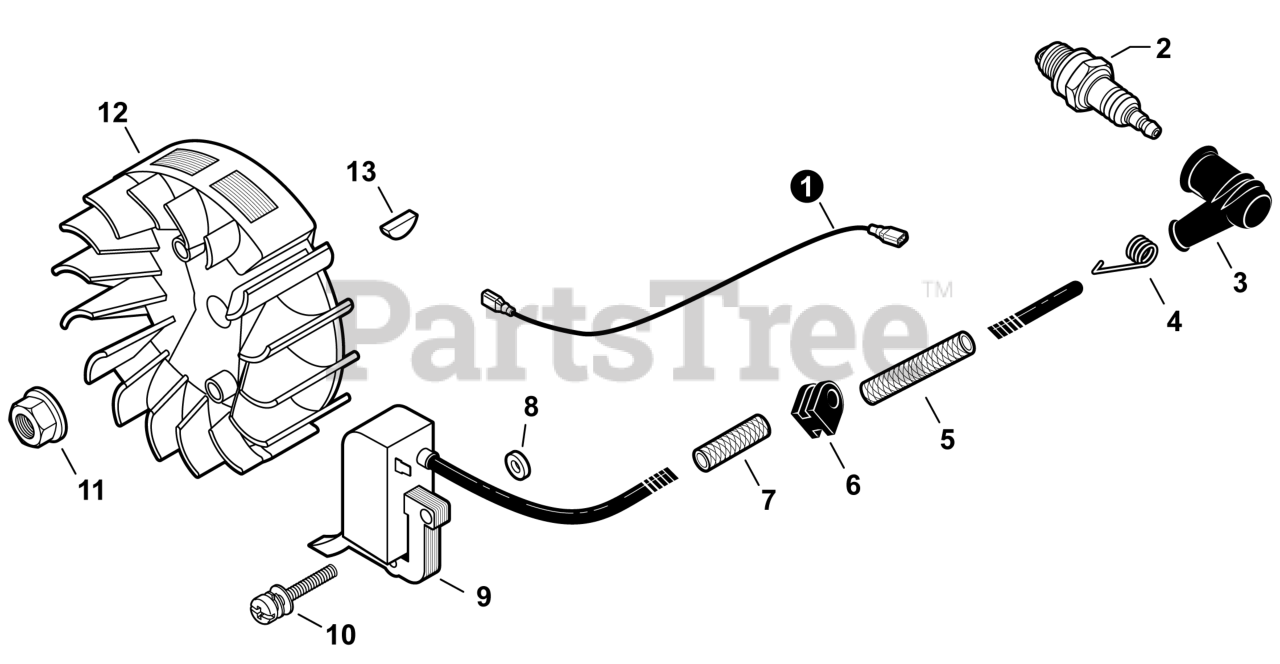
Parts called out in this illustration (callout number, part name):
1	LEAD - IGNITION L300
2	SPARK PLUG - BPMR8Y
3	CAP, SPARK PLUG
4	TERMINAL, SPARK PLUG
5	TUBE, INSULATOR 7×8.6×40
7	TUBE, INSULATOR
8	WASHER 5.2×12×3
9	COIL, IGNITION
10	SCREW 5×20
11	NUT, FLANGE M8
12	FLYWHEEL
13	KEY, WOODRUFF
